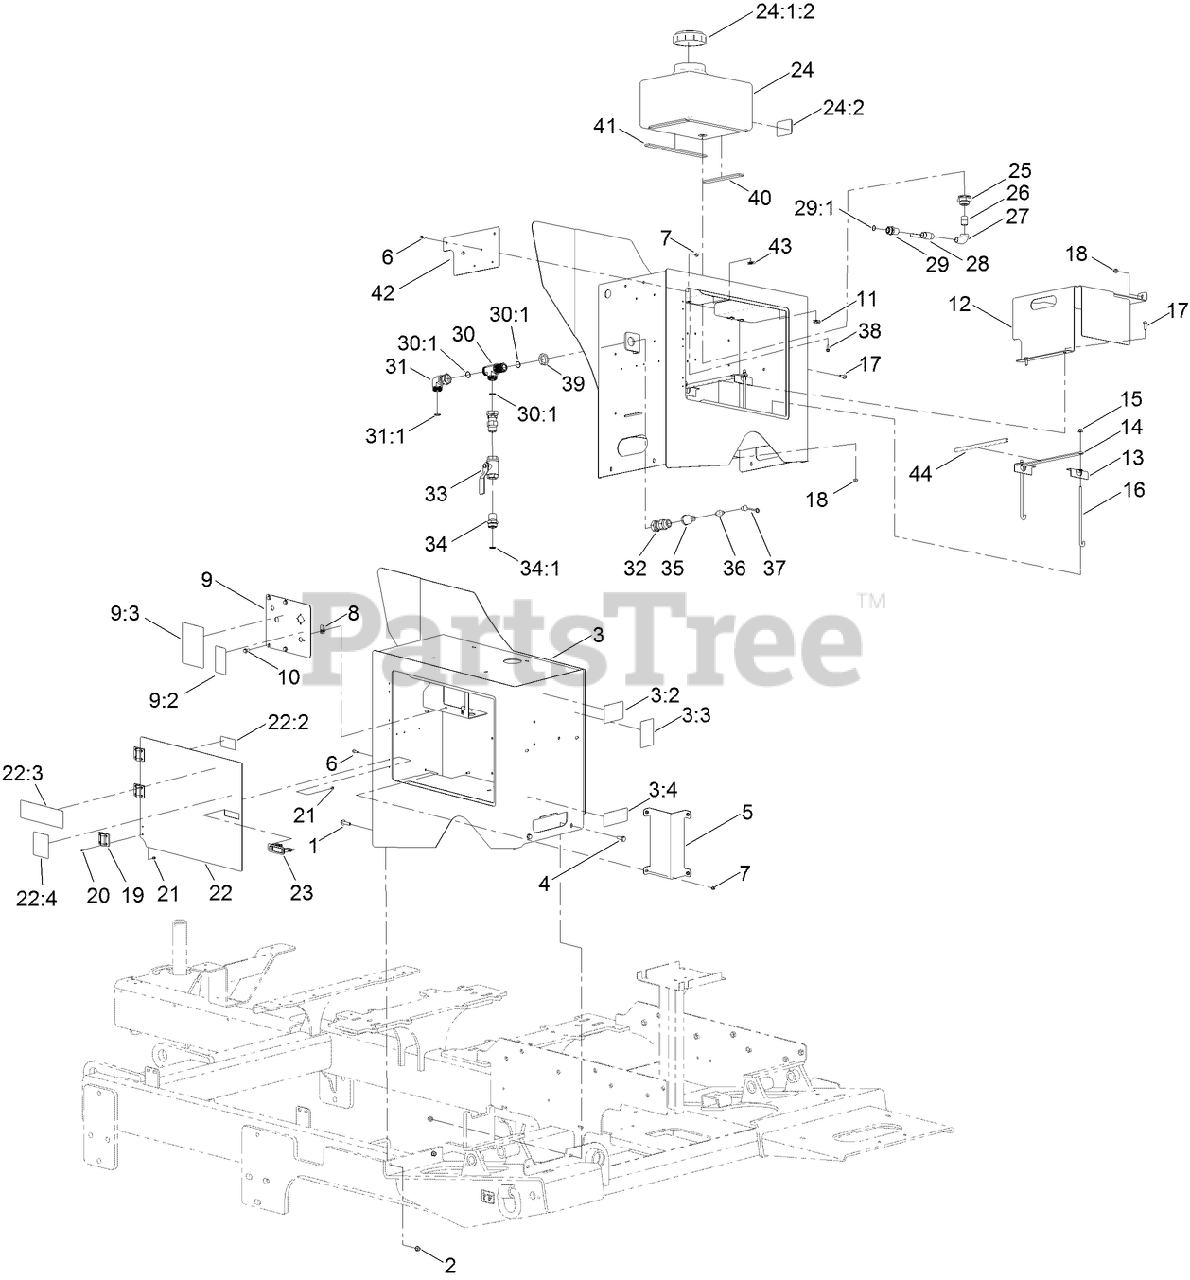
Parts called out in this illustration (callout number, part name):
1	SCREW-HHF
2	NUT-LOCK, NI
3	CONTROL BOX ASM
3:2	DECAL-RAISE AND LOWER
3:3	DECAL-DANGER, BACK UP
3:4	DECAL-WARNING, HYDRAULIC PRESSURE
4	SCREW-HHF
5	PLATE-CORNER, CONSOLE
6	SCREW-HHF
7	NUT-FLANGE, NI
9	CONTROL PLATE ASM
9:2	DECAL-DISCONNECT, BATTERY
9:3	DECAL-REAR CONTROLS OVERLAY
10	SCREW-HHF
12	PLATE-COVER
13	ANGLE-HOLDDOWN, BATTERY
14	PLATE-HOLD DOWN, BATTERY
15	NUT-HF, NI
16	BOLT-HOLDDOWN, BATTERY
17	SCREW-HHF
18	NUT-LOCK, HHF
21	NUT-HF
22	DOOR ASM
22:2	DECAL-WARNING, BATTERY
22:3	DECAL-SAFETY
22:4	DECAL-DANGER, NO RIDERS (REAR)
23	LATCH-TRIGGER, RAISED (W/LOCK)
24	ANTIFREEZE TANK ASM
24:1	TANK
24:1:2	LID-TANK
24:2	DECAL-ANTIFREEZE
25	FITTING-TANK, BULKHEAD (PLASTIC)
26	NIPPLE-STRAIGHT
27	ELBOW-STREET, 90 DEG
28	VALVE-BALL
29	FITTING-STRAIGHT
29:1	O-RING
30	FITTING-TEE, BULKHEAD
30:1	O-RING
31	FITTING-SWIVEL, 90 DEG
31:1	O-RING
32	FITTING-STRAIGHT
33	VALVE-BALL
34	FITTING-STRAIGHT
34:1	O-RING
35	FITTING-REDUCER
36	NIPPLE-CONNECT, QUICK
37	CAP-DUST
38	SCREW-HHF
39	NUT-BULKHEAD
40	STRIP-SEAL
41	STRIP-SEAL
42	PLATE-LOCKOUT, CYLINDER
44	TRIM-BATTERY
